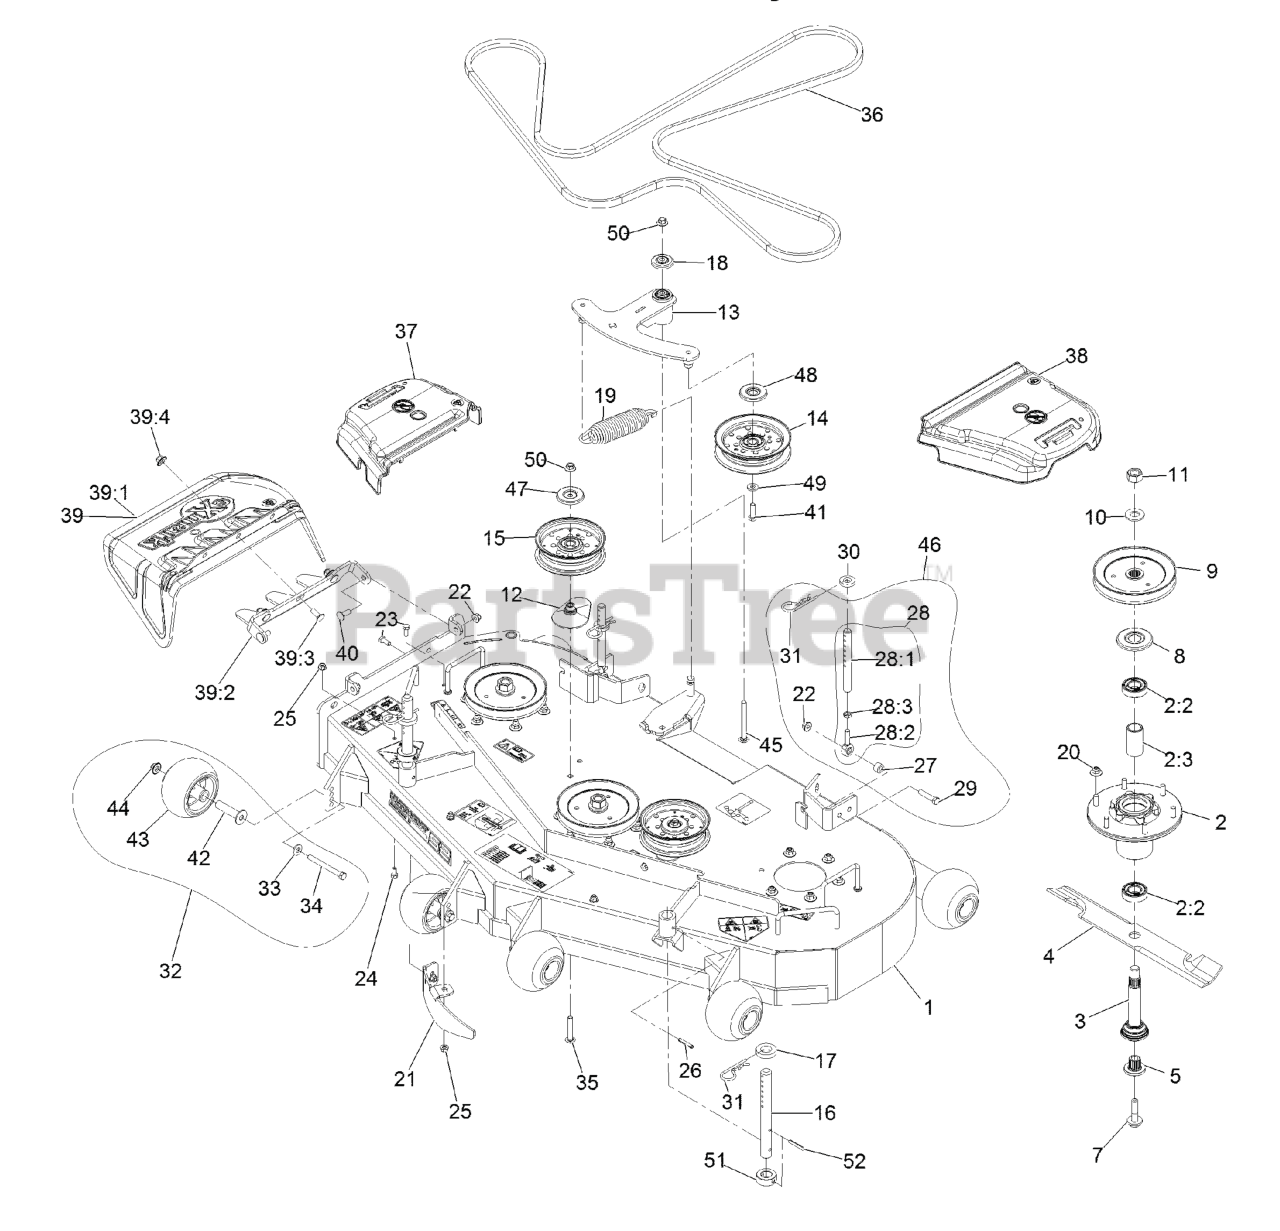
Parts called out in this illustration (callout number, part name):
1	ASM, DECK W/ DECALS, 52"
2	ASM-CUTTER HSG WITH BEARINGS
2:2	BEARING-BALL
2:3	SPACER-BEARING
3	ASM-SPINDLE AND SEAL
5	BUSHING,SPLINED
7	SCREW,SEMS 1/2-20 X 2.19
8	GUARD,BEARING TOP .989
9	SHEAVE,BLADE DRIVE 6.50
11	NUT-HEX
12	SPACER-PULLEY
13	ASM, DECK IDLER
15	IDLER-PULLEY, FLAT
16	ROD,DECK SUPPORT
17	SPACER-DECK SUPPORT
18	GUARD-TOP
19	SPRING-EXTENSION
20	Nut-Nyloc 3/8-16 Flg
21	BAFFLE, DOGLEG
22	NUT-HF, NI
23	SCREW-HH
24	SCREW-HH
25	NUT-HF, NI
28:1	LINK,SUPPORT
28:2	BALLJOINT
28:3	NUT-HJ
29	SCREW-HH
31	PIN,HAIR COTTER
32	KIT, ANTI-SCALP ROLLER
33	WASHER-BELLEVILLE
34	SCREW-HH 3/8-16 X 3 3/4 GR 8
35	BOLT-CARR, SHORT NECK
36	BELT, DECK
37	COVER-BELT, RH
38	COVER-BELT, LH
39	ASM, DISCHARGE CHUTE
39:1	CHUTE,DISCHARGE
39:2	BRACKET, DISCHARGE CHUTE
39:3	SCREW-CARR
39:4	Nut-Nyloc 3/8-16 Flg
40	SCREW-CARR
41	SCREW-HFH
42	AXLE, ROLLER
43	ROLLER-SCALP, ANTI
44	Nut-Nyloc 3/8-16 Flg
45	SCREW-CARR
46	KIT,SUPPORT LINK W/PIN
